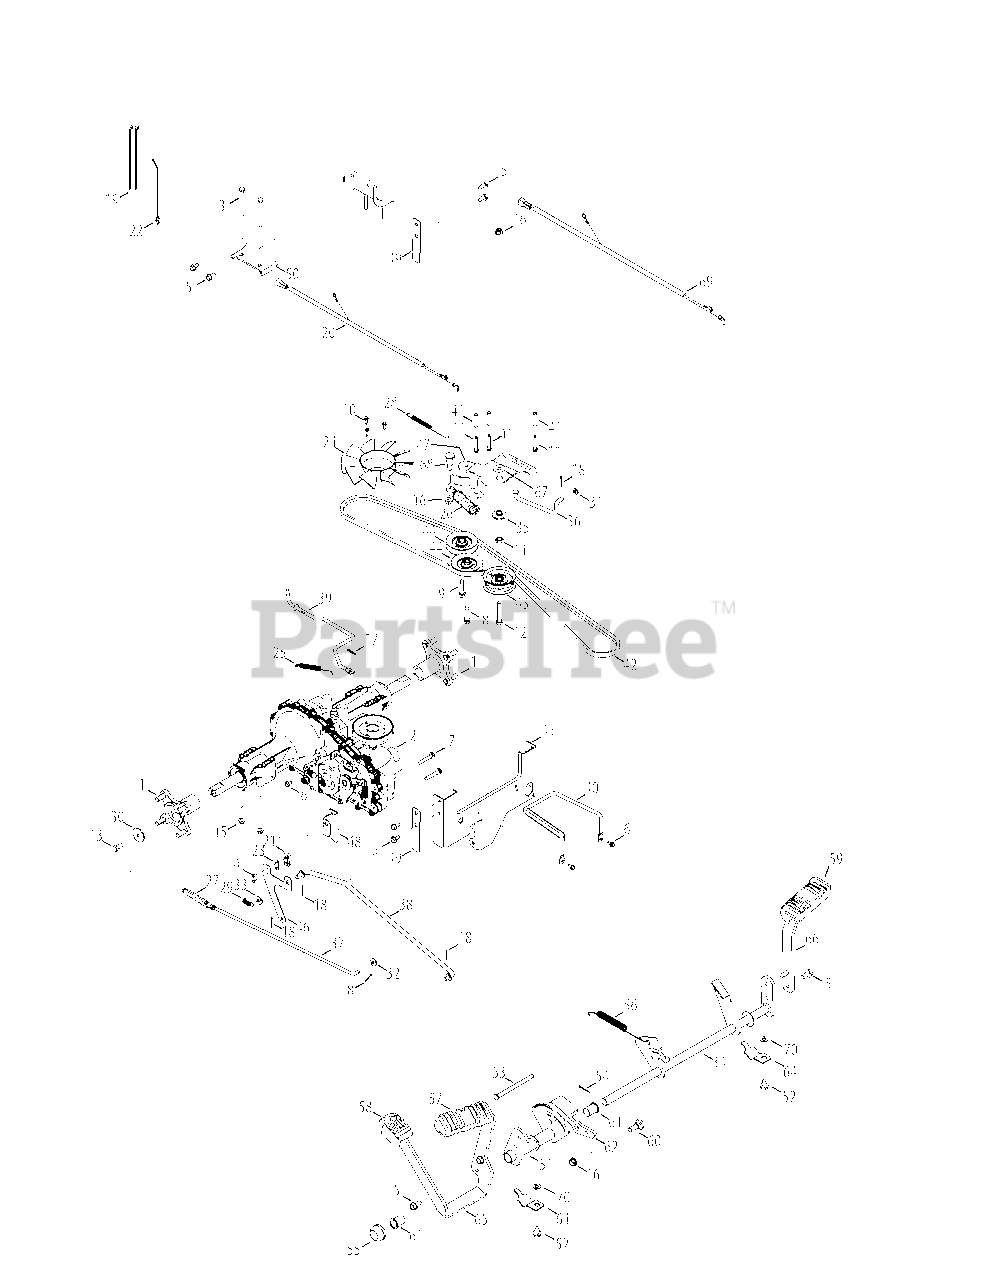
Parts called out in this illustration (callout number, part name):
1	Wheel Assembly Hub
2	Transmission
3	Hex Screw, 5/16-18 3.00
4	Screw, #8-18 0.500
5	Taptite Screw, 5/16-18 .750
6	Taptite Screw, 1/4-20 0.500
7	Taptite Screw, 5/16-18 1.750
8	Taptite Sems Screw, 3/8-16 1.500
9	Taptite Sems Screw, 3/8-16 1.875
10	Screw, #12-24 0.625
11	Taptite Screw, 1/4-20 1.75
12	Hex Screw, 3/8-16 2.25
13	Hex Screw, 3/8-16 .750
14	Jam Nut, 7/16-20
15	Flangelock Nut, 5/16-18
16	Flangelock Nut, 3/8-16
17	Cotter Pin, .072 DIA. x 1.13 LG
18	Cotter Pin, 3/32 1.0
19	Cable Tie, 3/16 x .05 x 7.4
20	Jumper Harness
21	Short Spring Switch
22	Push Mount Cable Tie 7.5 LG
23	Insulator Nut Plate
25	Extension Spring, .50 DIA x 5.0 LG
26	Extension Spring, 1.00 DIA x 4.75
27	Extension Spring, .59 OD x 4.00 LG
28	Extension Spring, .38 DIA x 5.6
29	Extension Spring, .375 OD x 1.44 LG
30	Flat Washer, .390 x 1.500 x .134
31	Flat Washer, .330 x .630 x .0635
32	Flat Washer, .344 x .750 x .120
33	Flat Washer, .407 x .812 x .135
34	Brake Control Assembly
35	Shoulder Spacer, 1.375 x .380 x .183
36	Footpedal Bypass Transmission Rod
38	Control Rod
39	Disengage Rod
40	Belt Keeper, 5/16
41	Spacer, 260 x .372 x 1.420 LG
42	V Belt, 4L x 77.0
43	Flat Idler Pulley, 2.75 OD
44	V Idler Pulley, 3.06
45	Torque Bracket
46	Switch Bracket
47	Center Idler Bracket
49	Plate Bracket
51	Hydro Pedal Bracket Assembly
52	Taptite Screw, 5/16-18 0.625
53	Clevis Pin, 5/16 x 3.985
54	Bow-Tie Cotter Pin
56	Extension Spring, .63 DIA x 4.95 LG
57	Pad, Pedal, Forward
58	Pad, Pedal, Reverse
59	Pad, Pedal, Brake
60	Shoulder Bolt, .500 x .270 3/8-16
61	Flange Bearing, .630 ID x .695 OD x .60
62	Cruise Latch
63	Pedal Support Bracket
64	Pedal Support Bracket, 5/8
65	Bracket, Pedal, Drive Hydro
66	Brake Pedal Bracket
67	Scr, Shldr, .50 x .685 3/8-16
68	Washer, Flat, .385 x 1.0 x .030
69	Jumper Harness, Ground & Reverse
70	Flat Washer, .344 x .688 x .065
